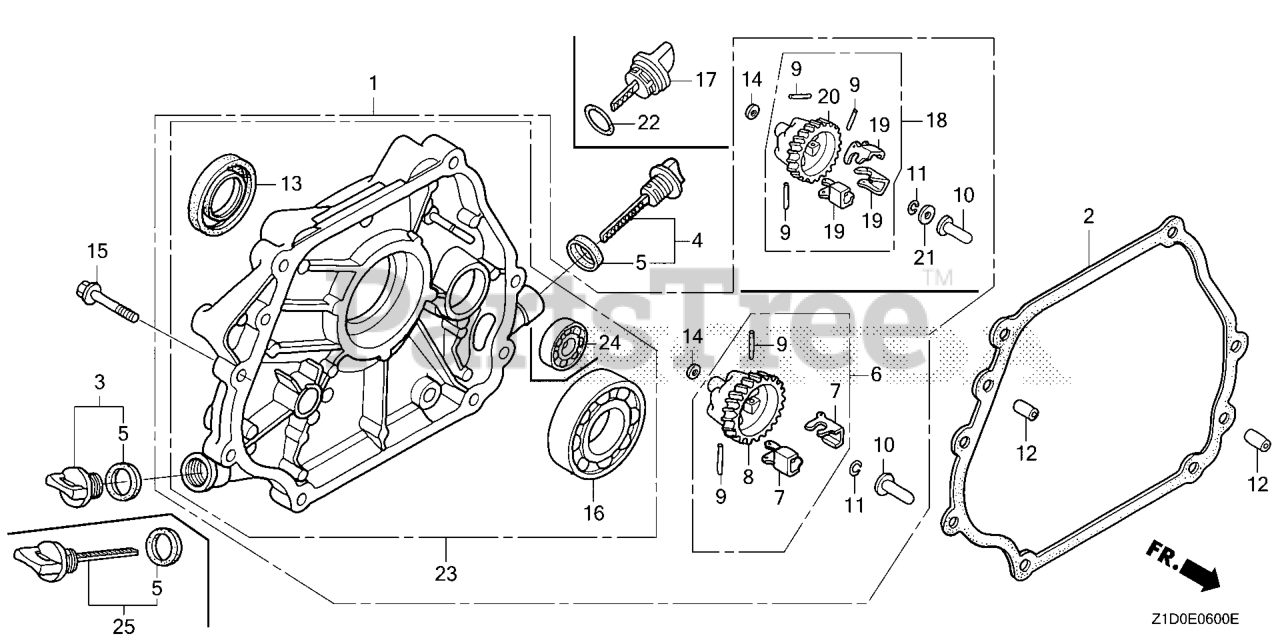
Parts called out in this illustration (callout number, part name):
1	COVER ASSY., CRANKCASE
2	GASKET, CASE COVER
3	CAP ASSY., OIL FILLER
4	CAP ASSY., OIL FILLER
5	GASKET, OIL FILLER CAP
6	GOVERNOR ASSY. (STD)
7	WEIGHT, GOVERNOR
8	HOLDER, GOVERNOR WEIGHT
9	PIN, GOVERNOR WEIGHT
10	SLIDER, GOVERNOR
11	CLIP, GOVERNOR HOLDER
12	PIN, DOWEL (8X12)
13	OIL SEAL (30X46X8) (NOK ASIA)
14	WASHER, PLAIN (6MM)
15	BOLT, FLANGE (8X35)
16	BEARING, RADIAL BALL (6206)
